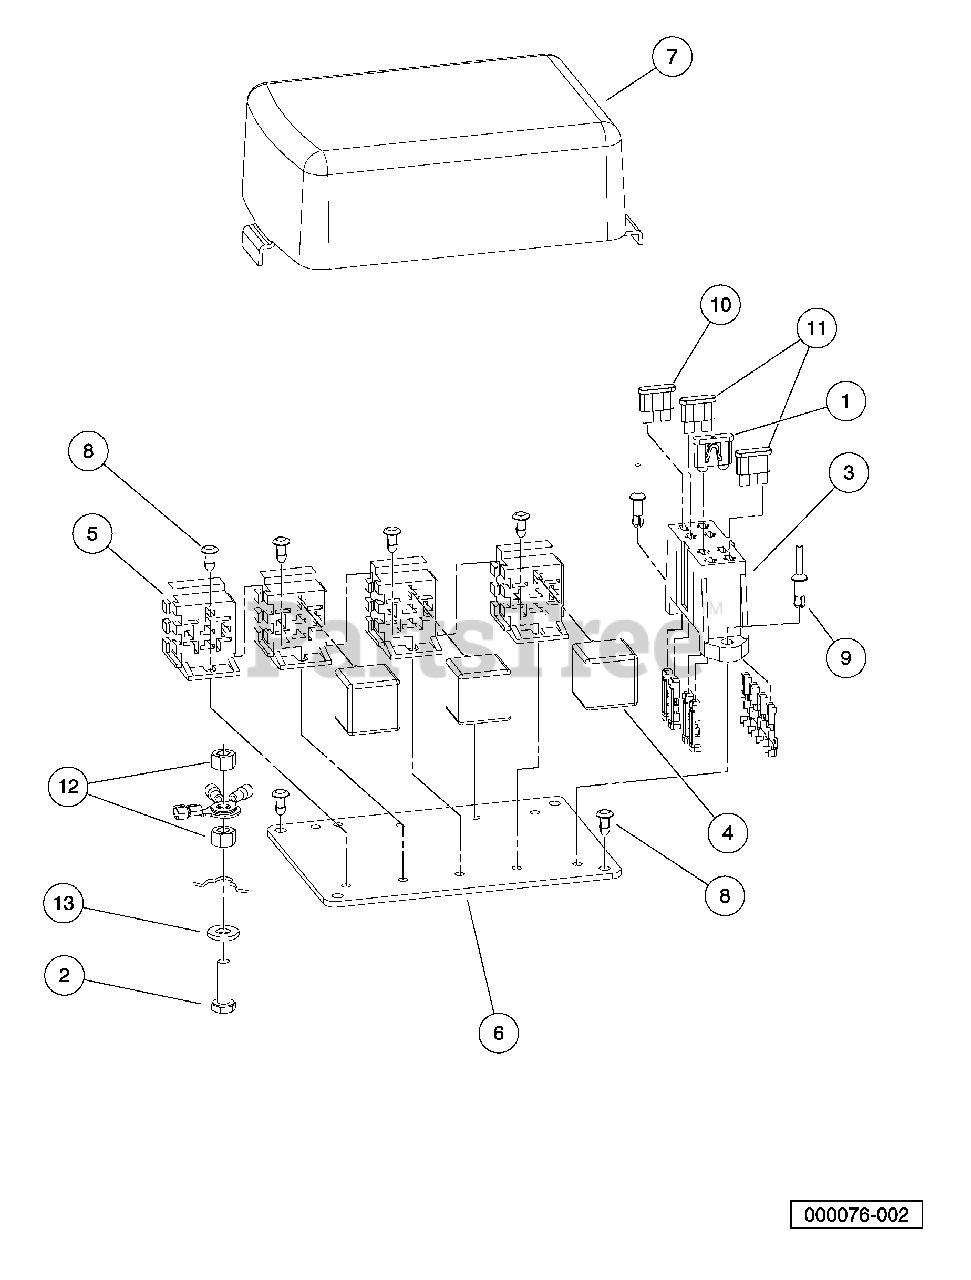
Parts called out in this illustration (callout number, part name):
1	Fuse, 10-Amp
2	Screw, 1/4-20 X .88 Hex Hd Cap
3	Fuse Block
4	Relay, Mini ISO, SPDT
5	Connector, Relay
6	Plate, Electrical
7	Cover, Electrical
8	Fastener, Push-in
9	Rivet, Drive
10	Fuse, 25-Amp
11	Fuse, 30-Amp
12	Locknut, 1/4-20 Dimpled
13	Washer, 1/4 Type A Narrow Flat
